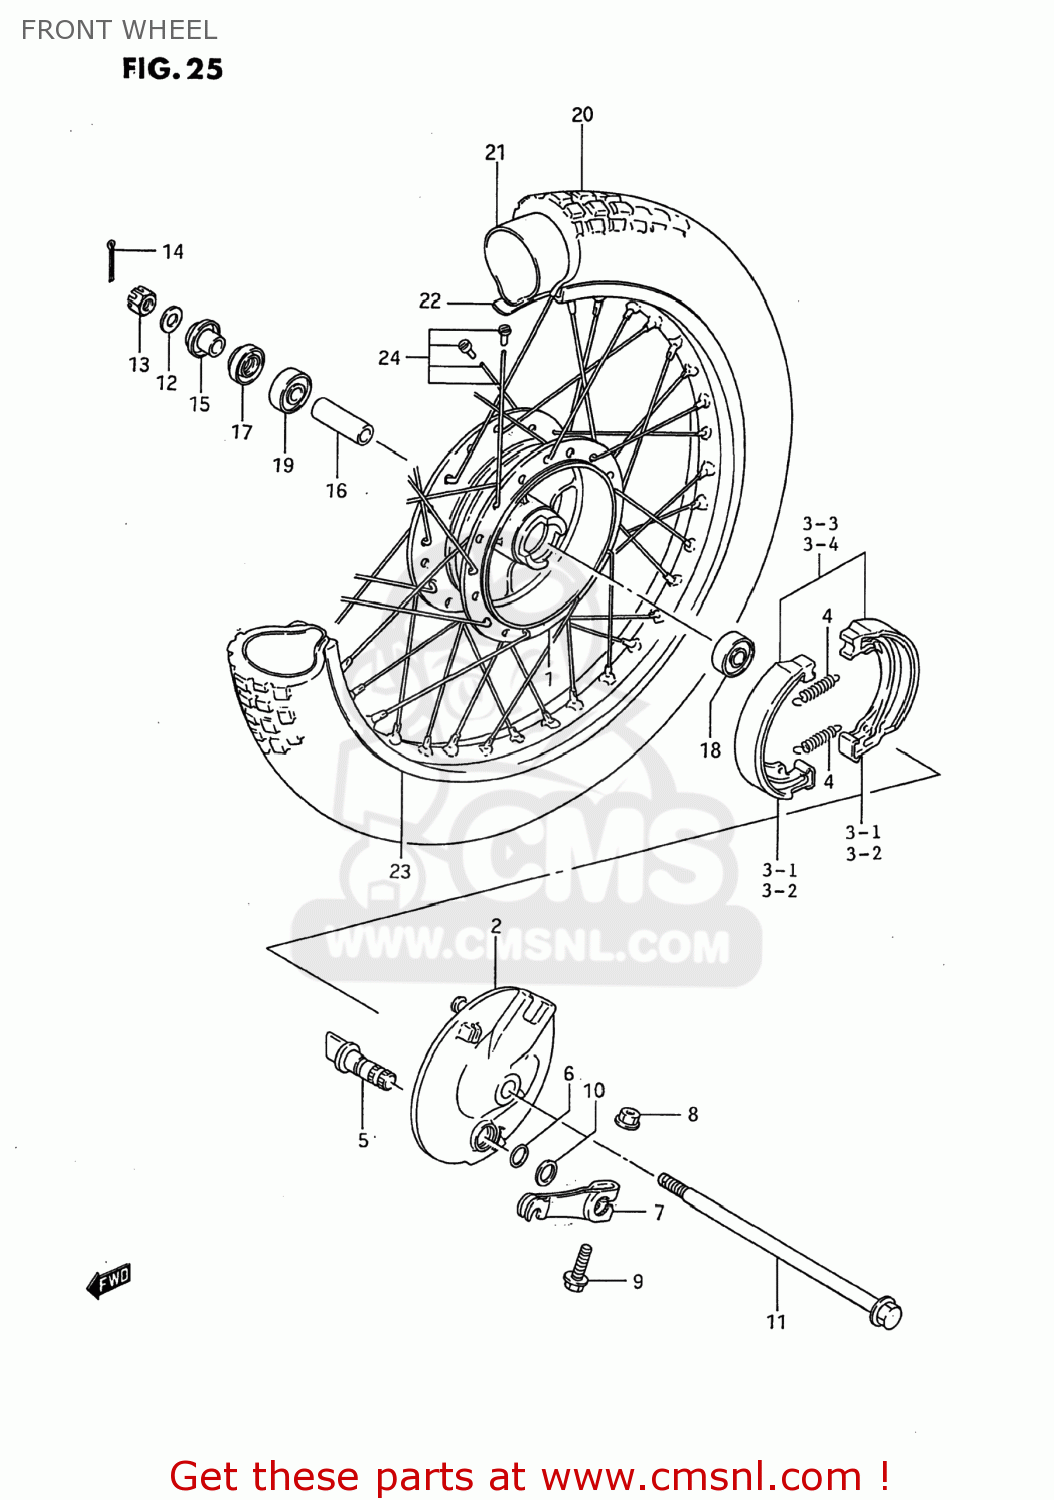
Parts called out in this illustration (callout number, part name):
1	HUB,FR
2	PANEL,FR BRAKE ANCHOR
3	SHOE,BRAKE
4	SPRING(L:35.8)
5	CAM,FR BRAKE
6	O-RING (D:2.4 ID:13.8)
7	LEVER,FR BRAKE CAM
8	NUT
9	BOLT
10	WASHER (14.5X22X1.6)
11	AXLE,FR
12	WASHER
13	NUT
14	PIN 20X20
15	SPACER,FR AXLE,R
16	SPACER (10.2X16X51)
17	SEAL,OIL(15X31X5)
18	BEARING
19	BEARING
20	TIRE(2.25 14)
21	TUBE,INNER
22	PROTECTOR,INNER TUBE
23	RIM,FR WHEEL(1.40X14)
24	SPOKE SET,FRONT
